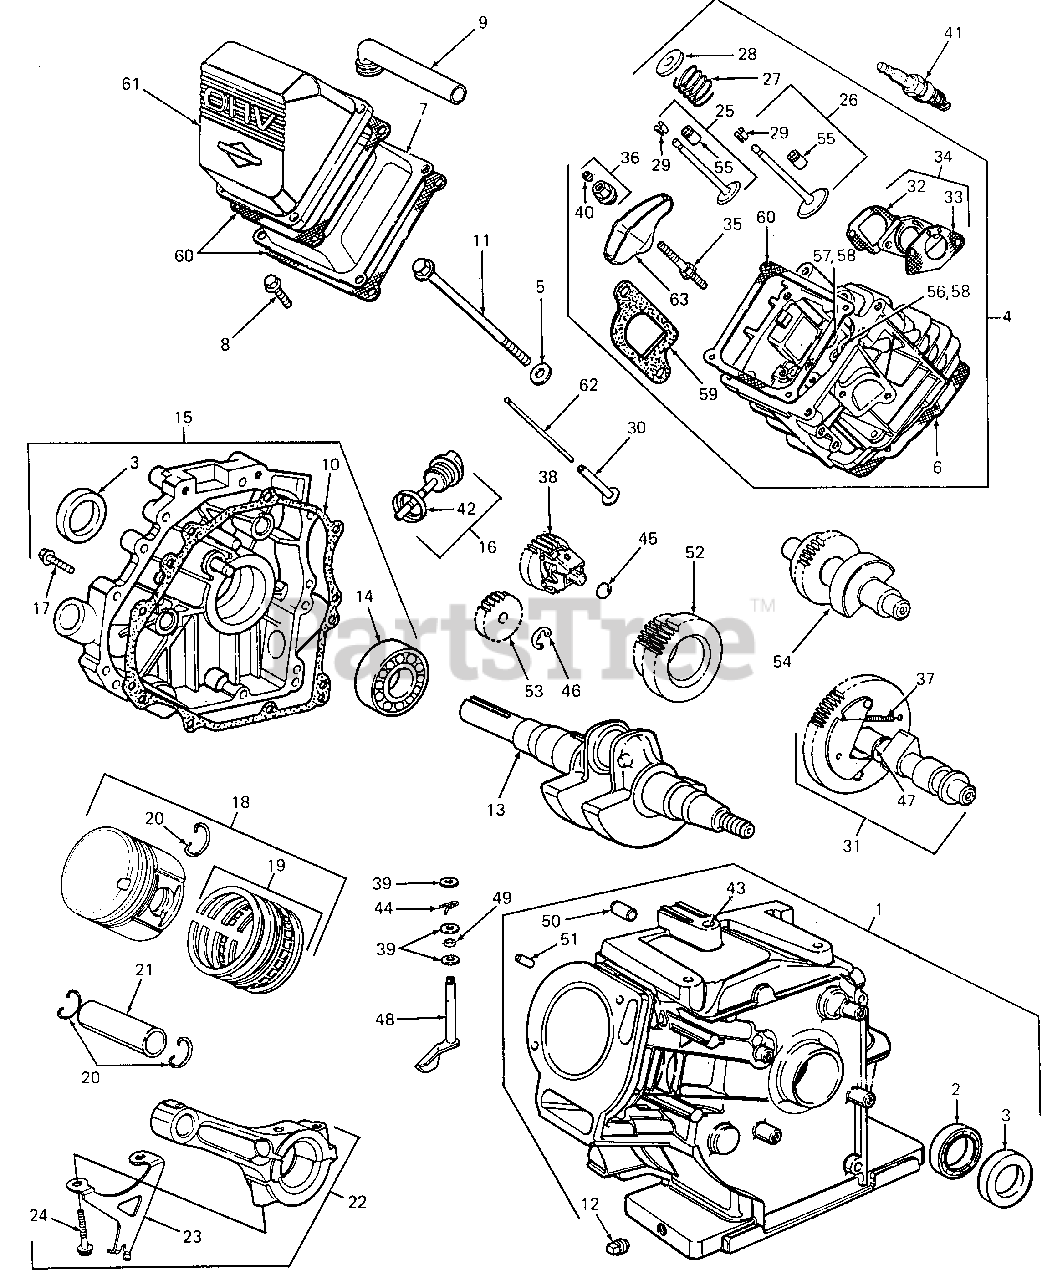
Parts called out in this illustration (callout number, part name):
1	Cylinder Assy
4	Head, Cylinder
6	Gasket, Cylinder Head
7	Breather Assy
8	Screw, Valve Cover
9	Tube, Breather
10	Gasket, Cover (1/64 Thk)
12	Plug, Oil Drain
13	Crankshaft
14	Bearing, Ball
15	Cover, Crankcase
16	Plug, Oil Filler
17	Screw, Cover
18	Piston Assy (Std)
19	Ring Set, Piston (Std)
20	Lock, Piston Pin
21	Pin Assy, Piston
22	Connecting Rod Assy
23	Dipper, Connecting Rod
24	Screw, Rod
25	Valve, Exhaust
26	Valve, Intake
27	Spring, Valve
28	Retainer, Intake Valve
29	Retainer, Valve Rotocoil
30	Tappet, Valve
32	Gasket, Adapter
33	Gasket, Adapter
34	Spacer, Carburetor
37	Spring, Cam
38	Gear, Governor
39	Washer, Crank
40	Screw, Set
41	Plug, Spark
42	Seal, Dipstick
44	Pin, Cotter
45	Ring, Retaining
46	Ring, Retaining
47	Ring, Retaining
48	Crank, Governor
50	Pin, Cylinder
51	Pin, Cylinder
52	Gear, Timing
53	Gear, Idler
54	Gear, Counterbalance
55	Seal Assy, Valve
56	Seat, Intake Valve
57	Seat, Exhaust Valve
58	Bushing, Valve Guide
59	Gasket, Muffler
60	Gasket, Rocker Cover
61	Cover, Valve
63	Arm, Rocker
